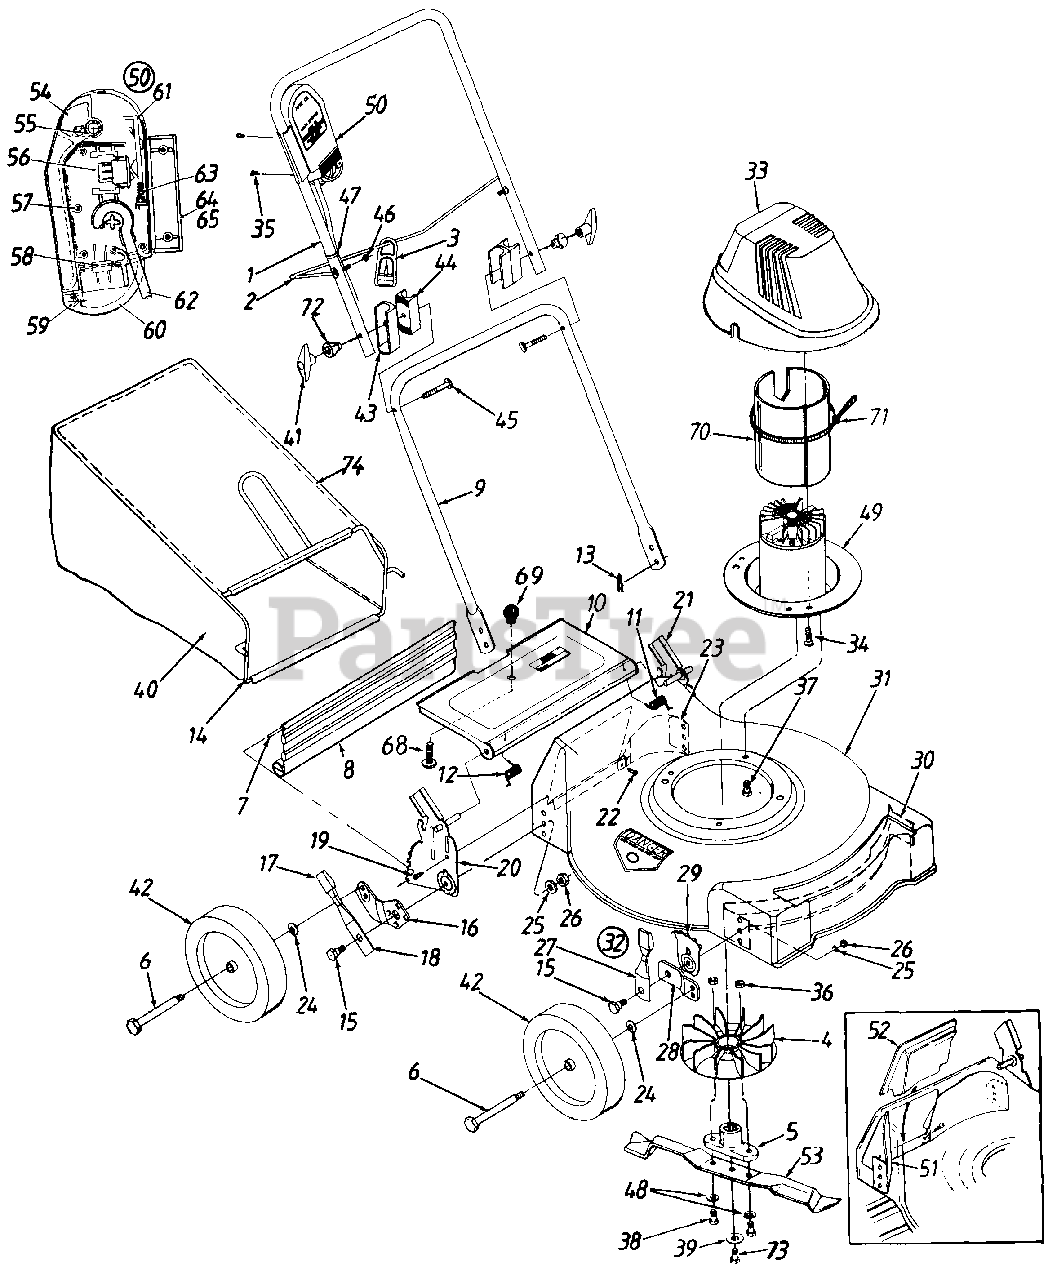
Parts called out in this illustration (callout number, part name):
3	Strain Relief - Cord
5	Blade Adapter
6	Axle Bolt
7	Rear Flap Wire
8	Rear Flap
12	Door Spring - R.H.
13	Hairpin Clip
16	Pivot Bar - R.H.
17	Spring Lever Knob
18	Spring Lever
19	Hex L-Wash. Hd. AB-Tap Scr. 1/4 x .62" Lg.
20	Handle Brkt. Ass'y.- R.H.
21	Handle Brkt. Ass'y.- L.H.
22	Torx. Mach. AB-Tap Scr. 1/4 x .62" Lg.
25	Bell-Wash. .39" I.D. x 1.38" O.D.
26	Hex Nut 3/8-16 Thd.
27	Spring Lever Ass'y. w/Knob
28	Pivot Bar
29	Height Adj. Plate
33	Motor Cover
34	Scr. #10-16 x .75" Lg.
35	Self-Tap. Scr. #7 x 1" Lg.
36	Hex Nut 3/8-24 Thd.
37	Hex L-Wash. TT-Tap Scr. 3/8-16 x .75" Lg.
38	Hex Bolt 3/8-24 x 1.25" Lg.
39	Bell-Wash. .396" I.D. x 1.14"
40	Grass Bag
41	Plastic Knob
42	Wheel Ass'y. Comp.
43	Upper Handle Insulator
44	Lower Handle Insulator
45	Carriage Bolt 5/16-18 x 3" Lg.
46	Hex Top L-Nut 1/4-20 Thd.
47	Cable Tie
48	Bell-Wash. 3/8" I.D.
49	Motor, Cord 8 Switch Ass'y.
50	Cord 8 Switch Ass'y. Comp.
53	19" Mulching Blade
54	Handle - Switch Actuator
55	Spring - Switch Handle
56	Switch
57	Screw 06-32 x .5" Lg.
58	Plug Ass'y.
59	Retainer Plug Spring
60	Retainer Plug
61	Latch
62	Cord Ass'y.
63	Spring Latch
64	Housing - Upper Half
68	Truss Scr. #10-24 x .38" Lg.
70	Insulator
71	Cable Tie
72	Insulator Knob
73	Hex Bolt 3/8-24 x 2.5" Lg.
